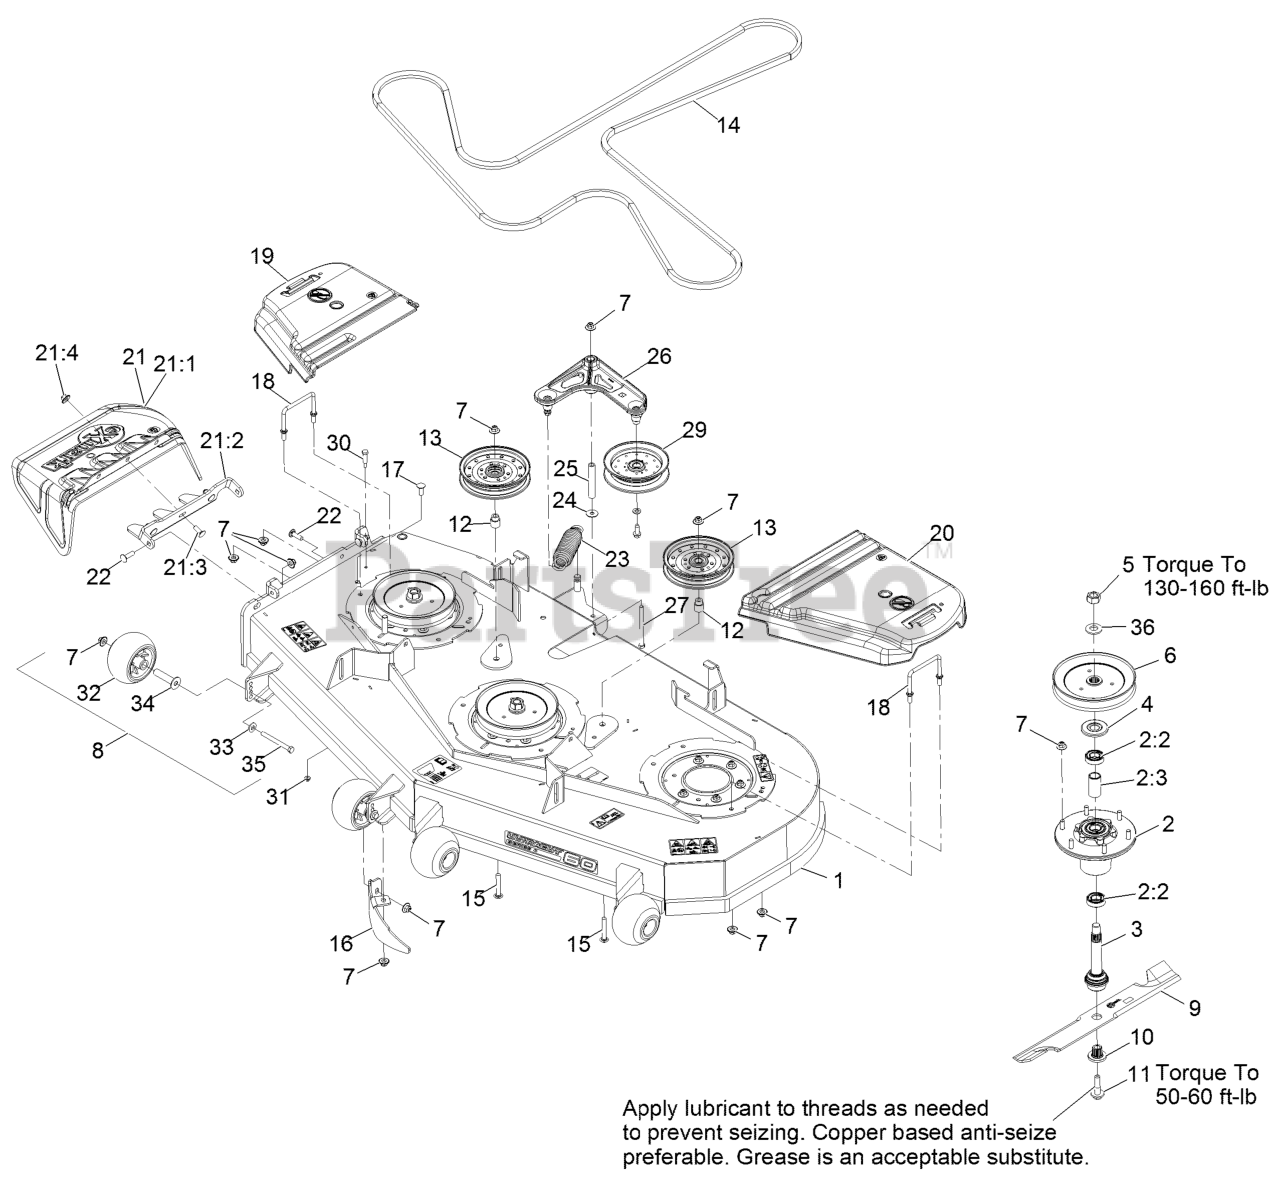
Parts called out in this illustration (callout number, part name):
1	DECK ASM,W/DECALS 604
2	ASM-CUTTER HSG WITH BEARINGS
2:2	BEARING-BALL
2:3	SPACER-BEARING
3	ASM-SPINDLE AND SEAL
4	GUARD,BEARING TOP .989
5	NUT-HEX
6	SHEAVE,BLADE DRIVE 7.25
7	Nut-Nyloc 3/8-16 Flg
8	KIT, ANTI-SCALP ROLLER
9	Blade-Extreme 2, 20.50"
10	BUSHING,SPLINED
11	SCREW,SEMS 1/2-20 X 2.19
12	BUSHING-IDLER
14	BELT-V
15	SCREW-CARR
16	DOGLEG - LZ60
17	SCREW-CARR
18	WIREFORM-COVER
19	COVER-BELT, RH
20	COVER-BELT, LH
21	ASM,DISCHARGE CHUTE
21:1	CHUTE,DISCHARGE
21:2	BRACKET,DISCHARGE CHUTE
21:3	SCREW-CARR
21:4	Nut-Nyloc 3/8-16 Flg
22	Bolt-Carriage 3/8-16 X 1 1/4
23	SPRING-EXTENSION
25	BUSHING
26	IDLER ARM ASM
27	SCREW-HH
30	BOLT-SHOULDER
32	ROLLER-SCALP, ANTI
33	WASHER-BELLEVILLE
34	AXLE, ROLLER
35	SCREW-HH 3/8-16 X 3 3/4 GR 8
